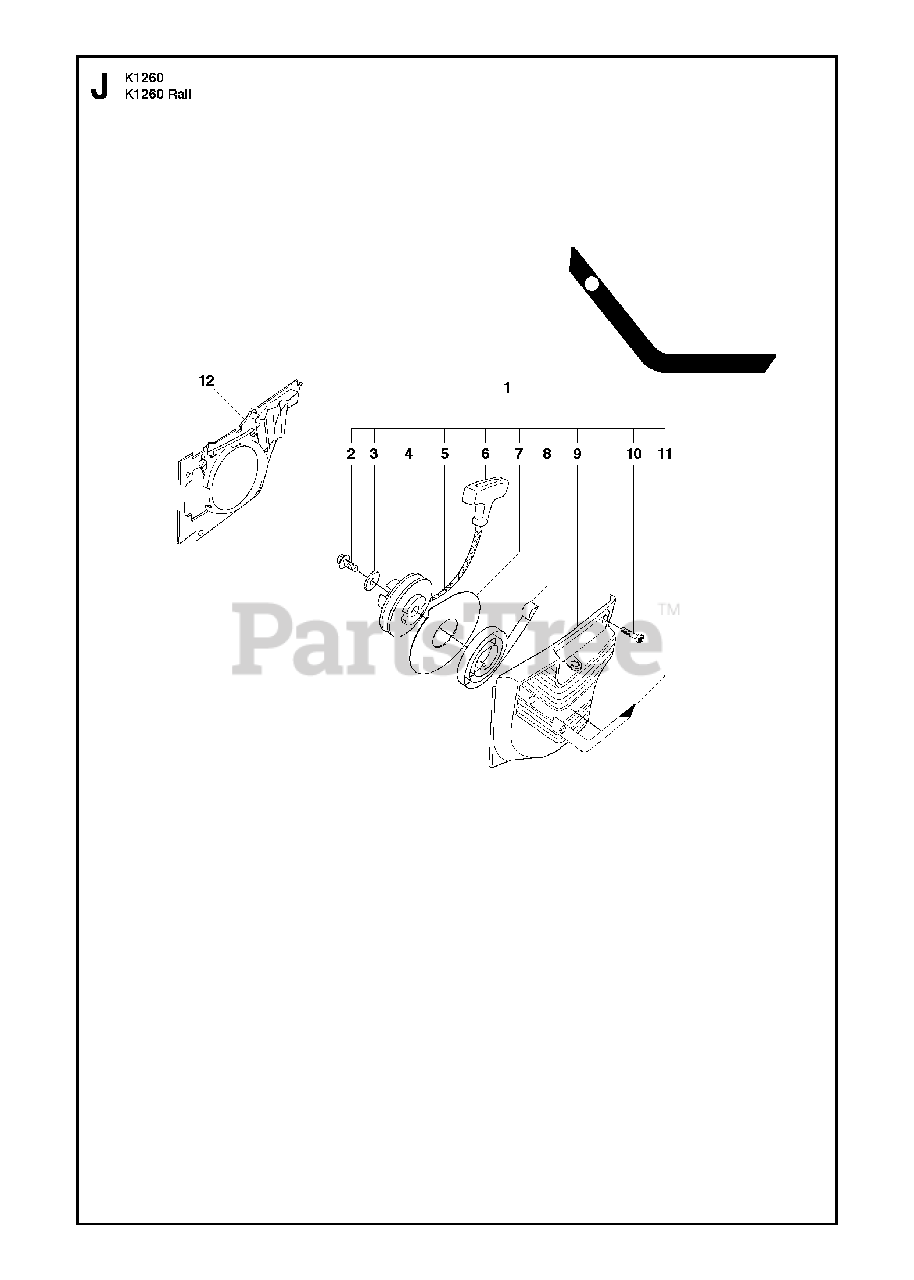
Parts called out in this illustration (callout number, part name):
1	STARTERIncl. 2 - 11
2	SCREW IHSCT
4	STARTER PULLEY
5	STARTER CORD
5	STARTER CORD50 meter
6	STARTER HANDLE
7	DAMPING DISC
8	RECOIL SPRING
9	STARTER COVER
10	SCREW ITXSCM
12	AIR CONDUCTOR
12	AIR CONDUCTORRail Stop Switch only
